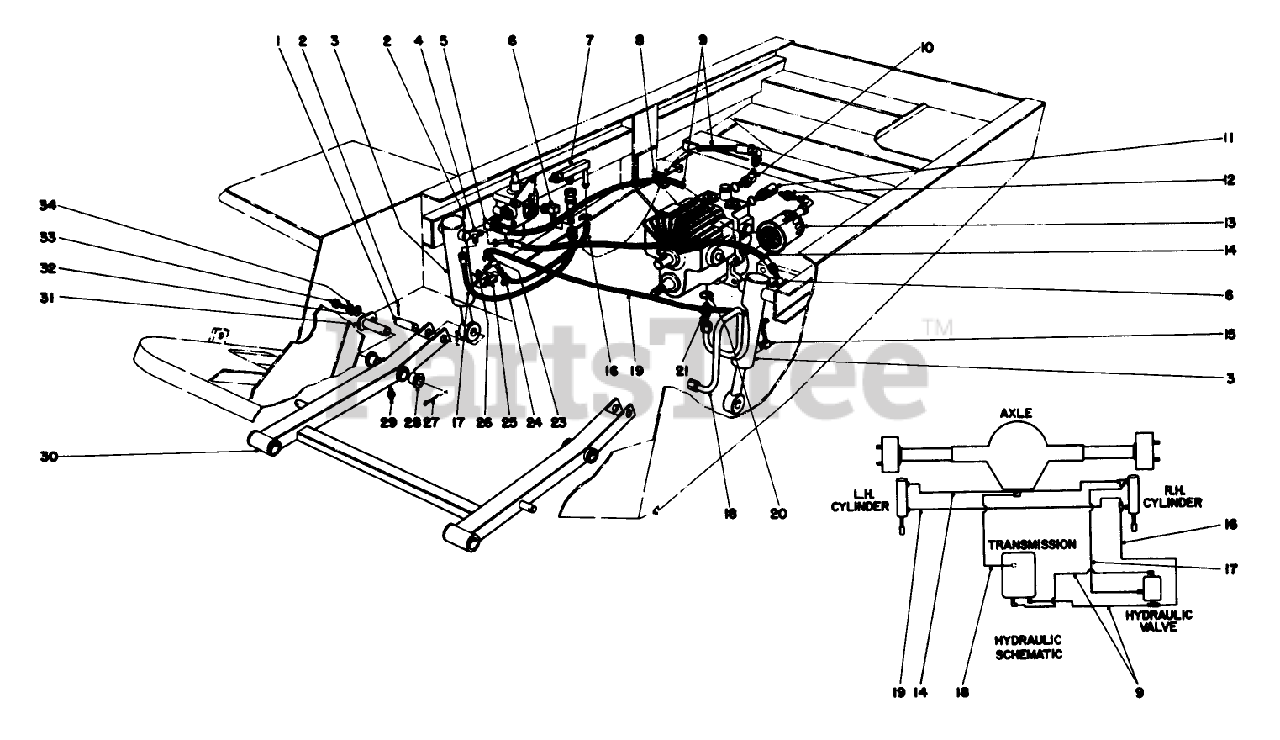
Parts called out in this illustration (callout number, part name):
1	PIN-CYLINDER
2	PIN-COTTER
3	Lift Cylinder
4	FITTING-TEE, ADJ.
5	FITTING-ELBOW, 90 DEG
6	FITTING-ELBOW, 90
7	Fitting Assembly
8	TIE-CABLE
9	TRANS-VALVE HOSE
10	FITTING-ELBOW, 45 DEG
11	SPECIAL FITTING PP
12	Adapter
13	FILTER-OIL, TRANSMISSION
14	RH CYL HOSE
15	STEM-HOSE
17	RH HOSE
18	HYORAULIC TUBE
19	HOSE-FUEL
20	O-RING
21	FITTING-STRAIGHT
23	MALE TEE FITTING
24	CLAMP-HOSE
25	CONN FITTING
26	O-RING
27	PIN-COTTER
28	7/8 ID X 1.128 X 7/8 LG BSHG
29	GREASE FITTING
30	Lift Arm (Incl. Ref. #28-29)
31	Pin-Pivot
32	WASHER-FLAT
33	SCREW-HH
34	WASHER-LOCK
